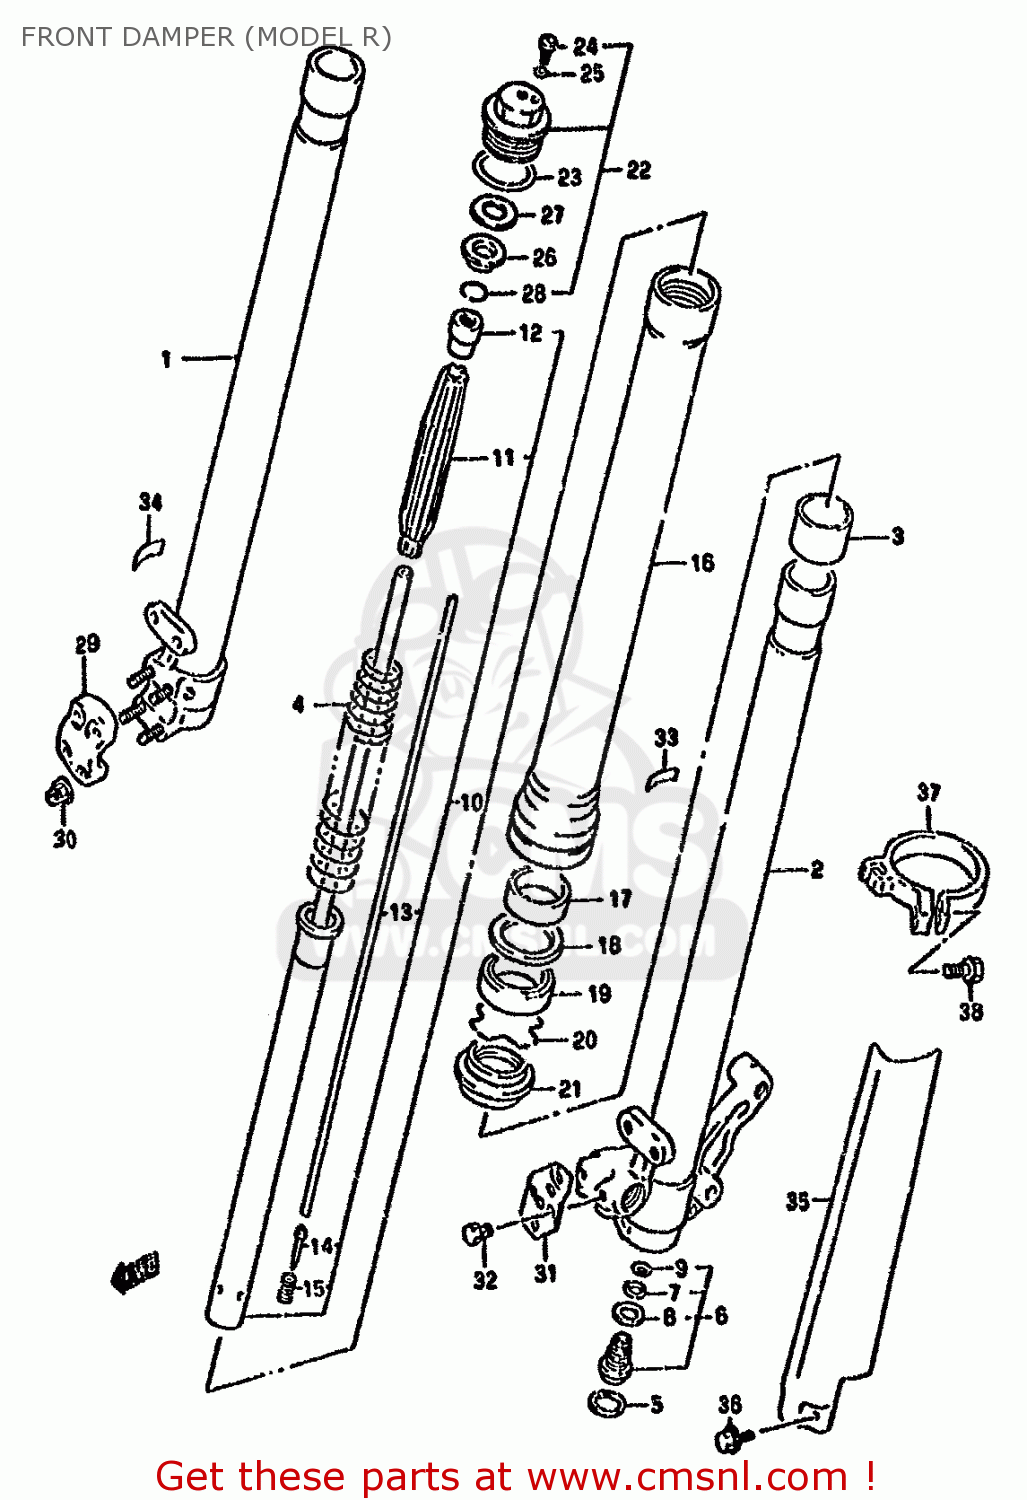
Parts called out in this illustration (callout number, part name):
1	TUBE,INNER,RIGHT
2	TUBE,INNER,L
3	BUSH,SLIDE
4	SPRING,MAIN
5	RING,CTR BOLT STOPPER
6	BOLT ASSEMBLY,CENTER
7	O RING,CTR BOLT
8	GASKET (NAS)
9	O RING,CTR BOLT UPR
10	CYLINDER
11	GUIDE,PUSH ROD SPRING
12	NUT,ROD
13	ROD,PUSH
14	NEEDLE
15	SPRING,PUSH ROD
16	TUBE,OUTER
17	BUSH,GUIDE
18	SPACER,SEAL
19	SEAL,OIL
20	RING,OIL SEAL STOPPER
21	SEAL,DUST
22	BOLT ASSY,FORK
23	O RING
24	BOLT,PLUG
25	O RING
26	SEAT,SPRING
27	WASHER,THRUST
28	RING,STOPPER
29	HOLDER,AXLE,R
30	NUT
31	GUIDE,HOSE,L
32	BOLT
33	LABEL
34	LABEL
35	PROTECTOR,FORK,R
36	BOLT,PROTECTOR(6X10)
37	GUIDE,FORK PROTECTOR
38	BOLT,PROTECTOR GUIDE,6
